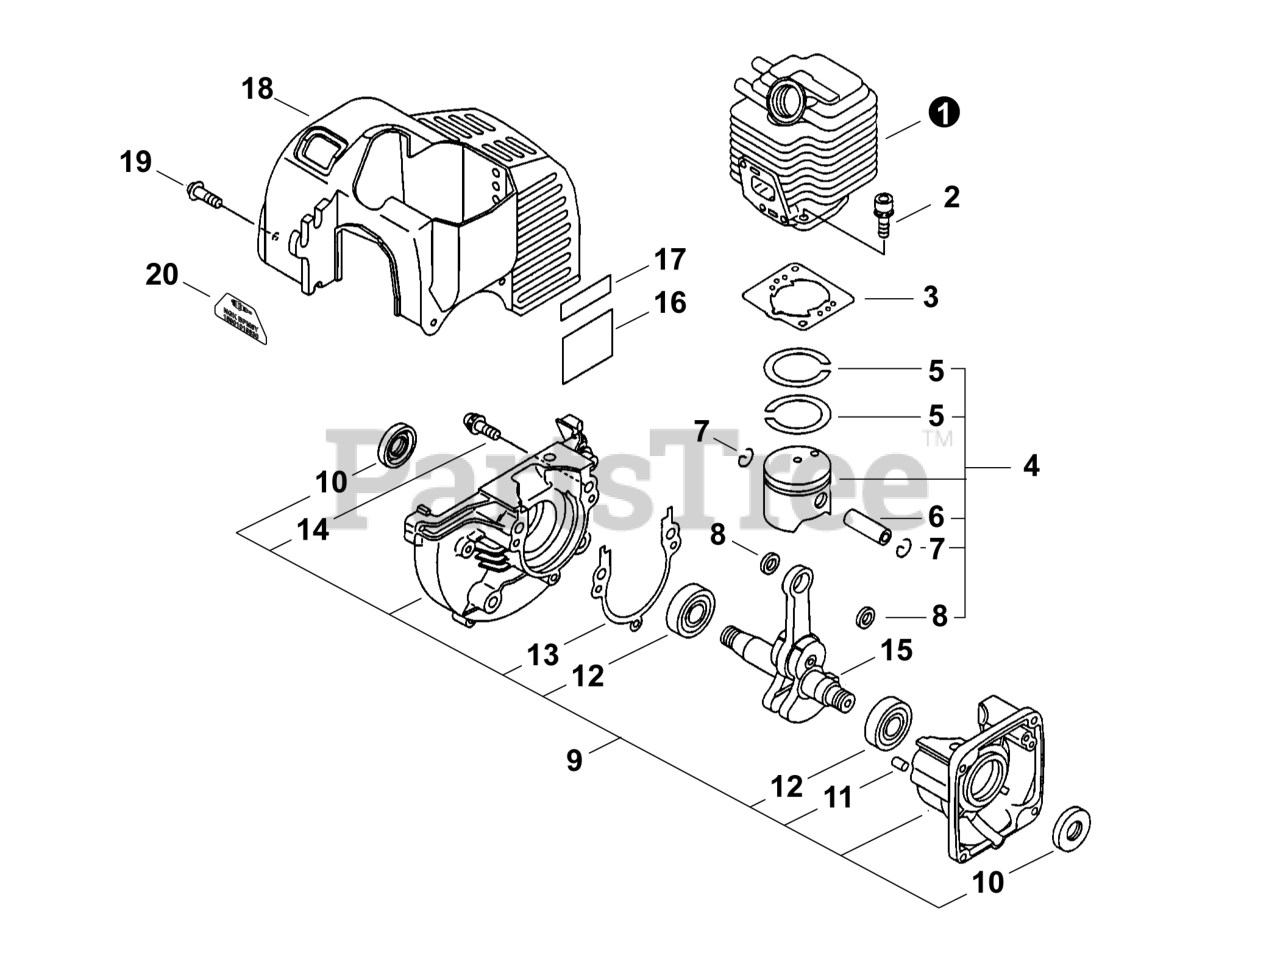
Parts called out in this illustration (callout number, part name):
1	CYLINDER
2	BOLT 5×22
3	GASKET, CYLINDER
4	PISTON KIT
5	RING, PISTON
6	PIN, PISTON 8
7	RING, SNAP
8	WASHER, THRUST
9	CRANKCASE KIT
10	SEAL, OIL 12
11	PIN, LOCATING 4×8
12	BEARING, BALL 6201
13	GASKET, CRANKCASE
14	BOLT 5×28
15	CRANKSHAFT ASSY
16	LABEL - CAUTION
17	LABEL - MODEL
18	COVER, CYLINDER
19	SCREW 4×12
20	LABEL - SPARK PLUG - BPM8Y
